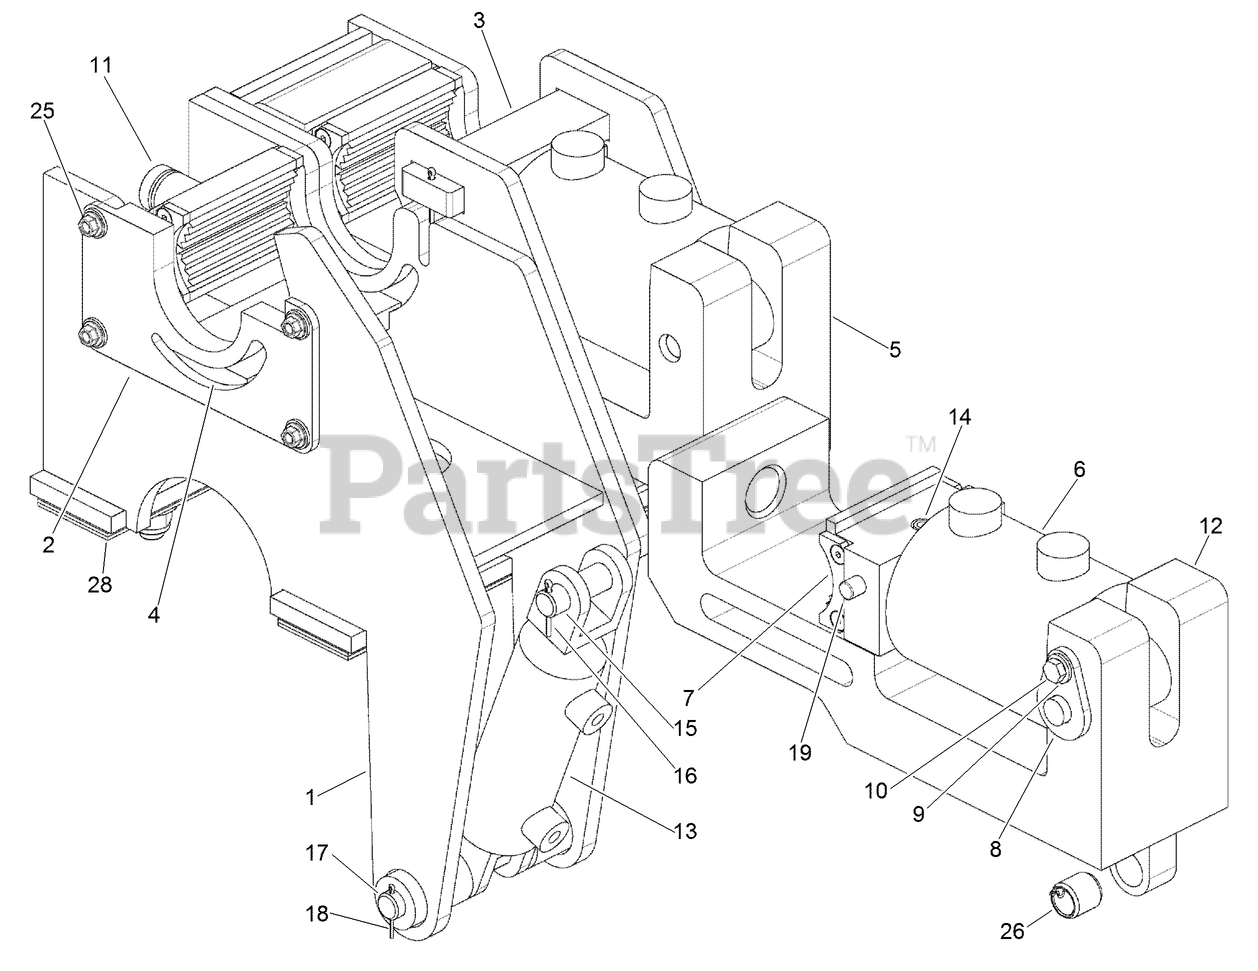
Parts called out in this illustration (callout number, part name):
1	WELDMENT - Wrench, DD1215
2	RETAINER - Pivot Key, Wrench
3	PIN - Retaining, Die Holder
4	KEY-PIVOT, WRENCH
5	BASE - Fixed Clamp, Wrench
6	CYLINDER - Hydraulic, 4 Bore x 1.75 Stroke
7	MOVING DIE HOLDER ASM
8	PIN-FLAGGED
9	WASHER-FLAT
10	SCREW-HH
11	FIXED DIE HOLDER ASM
12	ROTATING CLAMP - Wrench
13	HYD CYLINDER ASM
14	PIN-SPRING
15	PIN-CLEVIS
16	PIN-Cotter, 1/8 x 1-1/4 in ZN
17	PIN-CYLINDER
18	PIN - Cotter, .094 x 1.25 in ZN
19	PIN-DOWEL
25	SCREW, METRIC FLANGE w/BODY - M8 x 20
26	BUSHING-SPRING
28	PLATE - Shim
